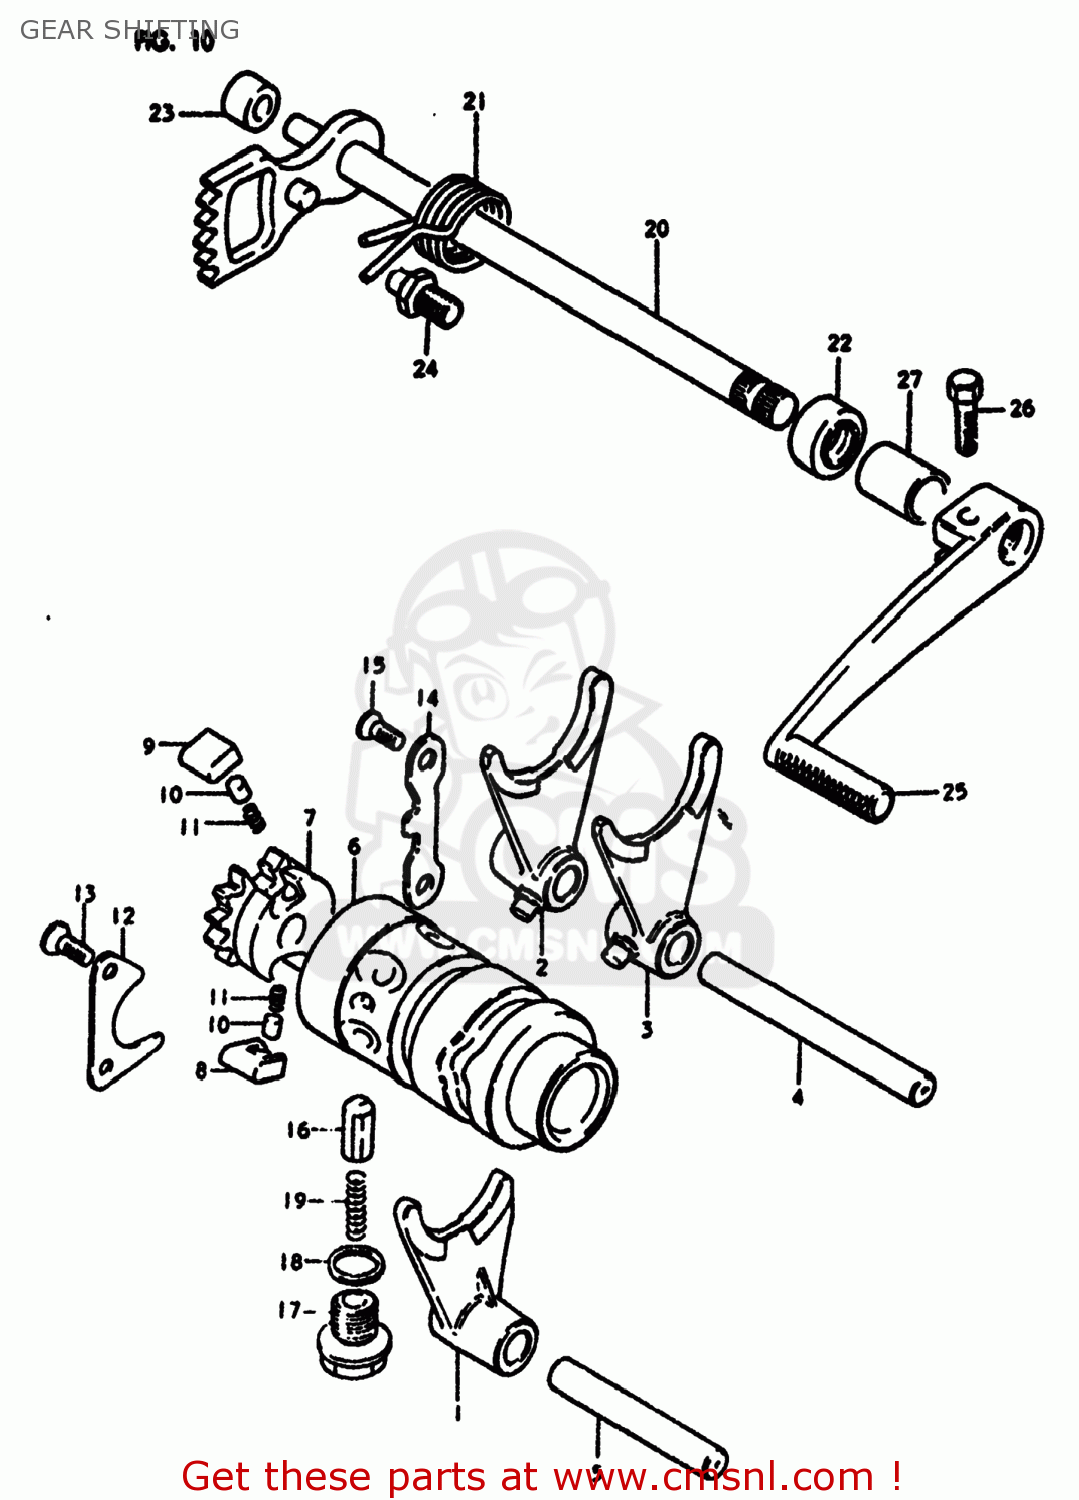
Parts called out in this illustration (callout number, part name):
1	FORK,GEAR SHIFT NO.1
2	FORK,GEAR SHIFT NO.2
3	FORK,GEAR SHIFT NO.3
4	SHAFT,GEAR SHIFT FORK
5	SHAFT,GEAR SHIFT FORK
6	CAM,GEAR SHIFT
7	RETAINER,GEAR SHIFT CAM
8	PAWL,GEAR SHIFT NO.1
9	PAWL,GEAR SHIFT NO.2
10	PIN(5X8)
11	SPRING
12	LIFTER,GEAR SHIFT PAWL
13	SCREW
14	GUIDE,GEAR SHIFT CAM
15	SCREW
16	STOPPER,GEAR SHIFTING
17	BOLT,GEAR SHAFT CAM STOPPER
18	GASKET(14X19.2X2) (NAS)
19	SPRING
20	SHAFT,GEAR SHIFT
21	SPRING
22	OIL SEAL
23	SPACER(12X20X15.3)
24	STOPPER,GEAR SHIFT CAM
25	LEVER ASSEMBLY,GEAR SHIFTING
26	BOLT
27	CUSHION
